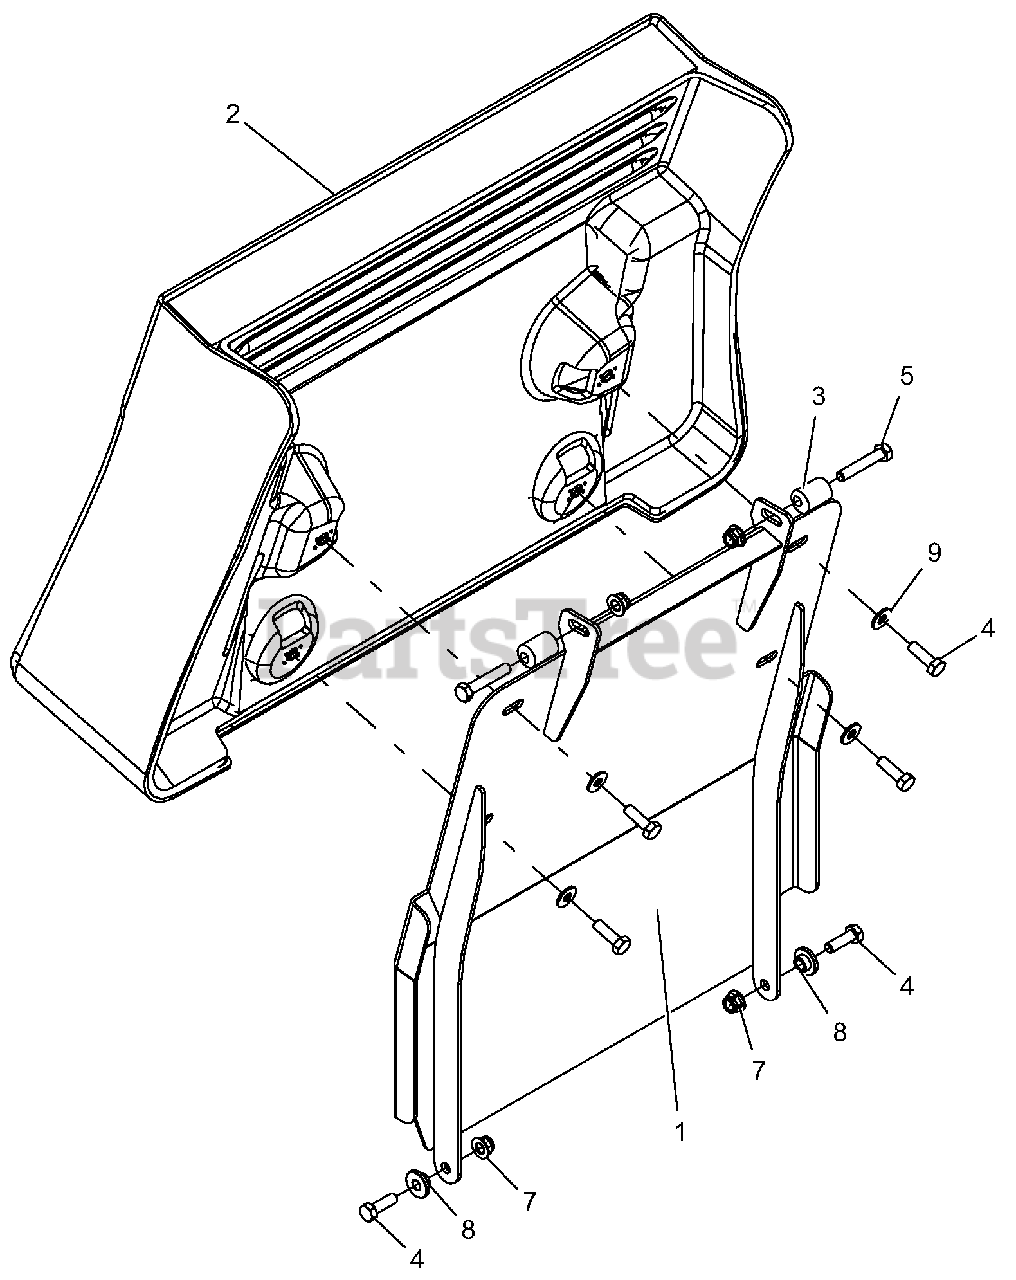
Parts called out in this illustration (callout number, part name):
1	WLDMT, PAD MOUNT
2	PAD, PROSTANCE
3	ECCENTRIC
4	BLT-HEX .31-18 x 1.00 GR5 YWZC
5	BLT-HEX .31-18 x 1.75 GR5 YWZC
7	NUT-LK-NYL-FLG .31-18 YWZC
8	BSHG, FLG .32 x .500 .344 x .880
9	WSHR-FL-STL .312 x .734 x .065 YWZ
